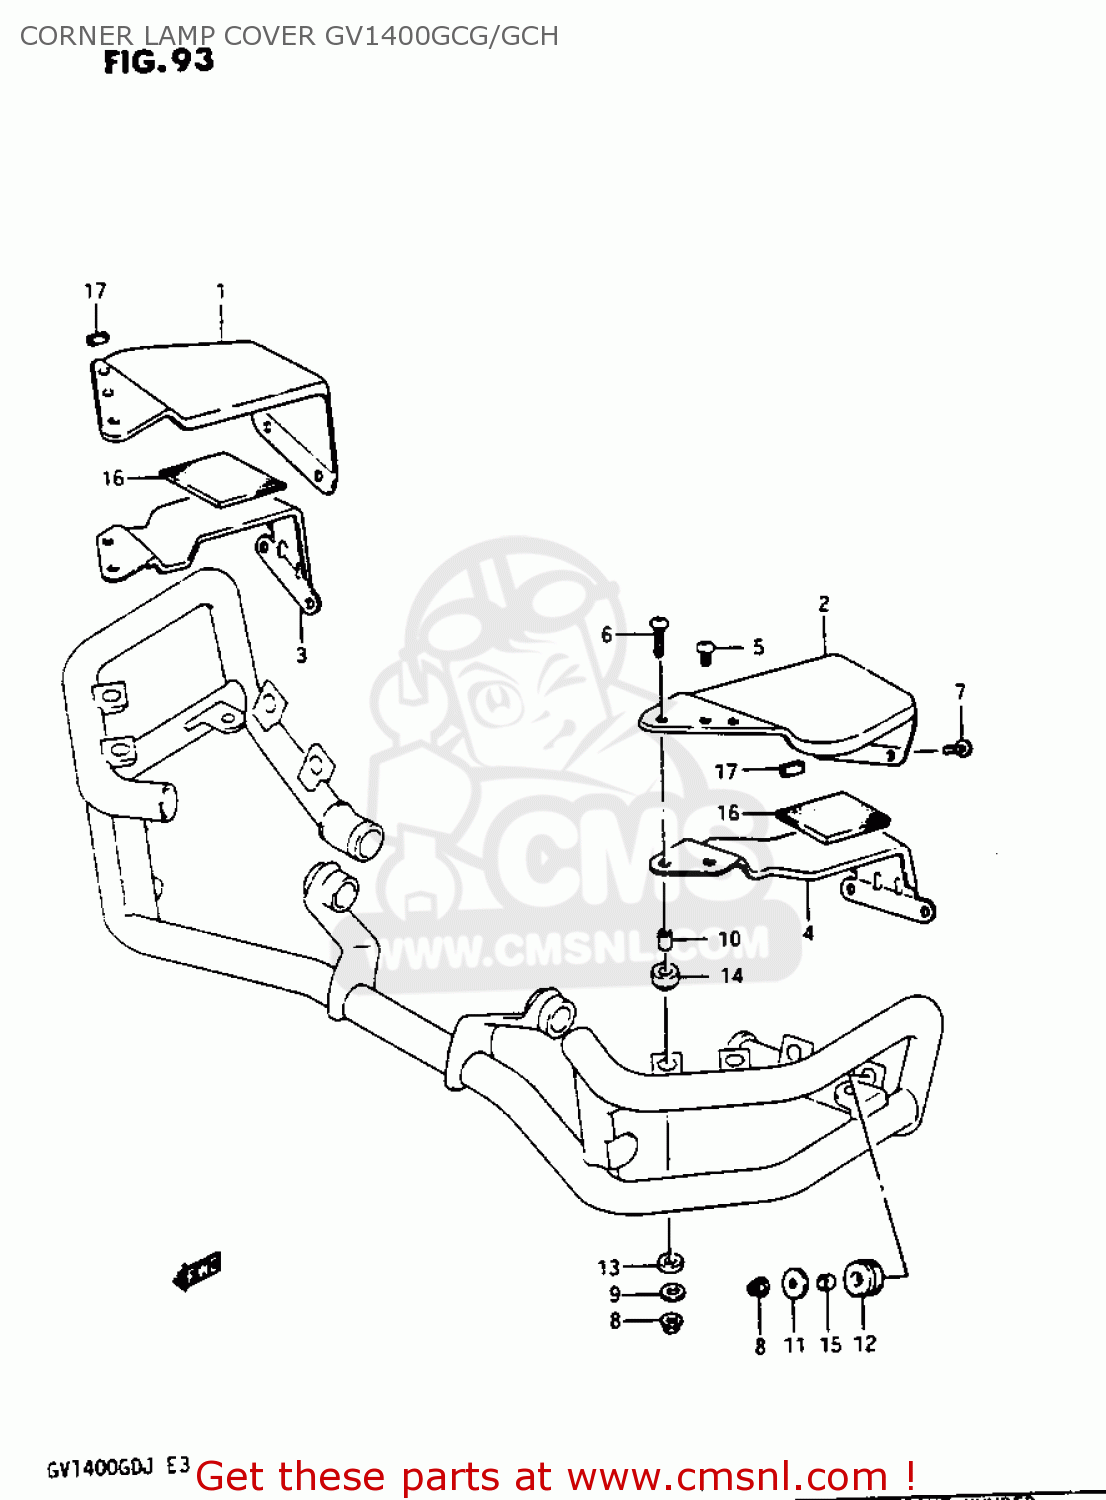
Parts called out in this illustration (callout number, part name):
1	COVER,CORNER LAMP,RIGHT
2	COVER,CORNER LAMP,LEFT
3	COVER,CORNER LAMP,LOWER
4	COVER,CORNER LAMP,LOWER
5	SCREW
6	SCREW
7	SCREW
8	NUT
9	WASHER (5.5X14X1.2)
10	SPACER
11	WASHER (5.5X20X1.2)
12	CUSHION
13	CUSHION
14	CUSHION
15	SPACER(6.1X9X7.5)
16	CUSHION,CORNER LAMP CVR CTR
17	CUSHION, SIDE
